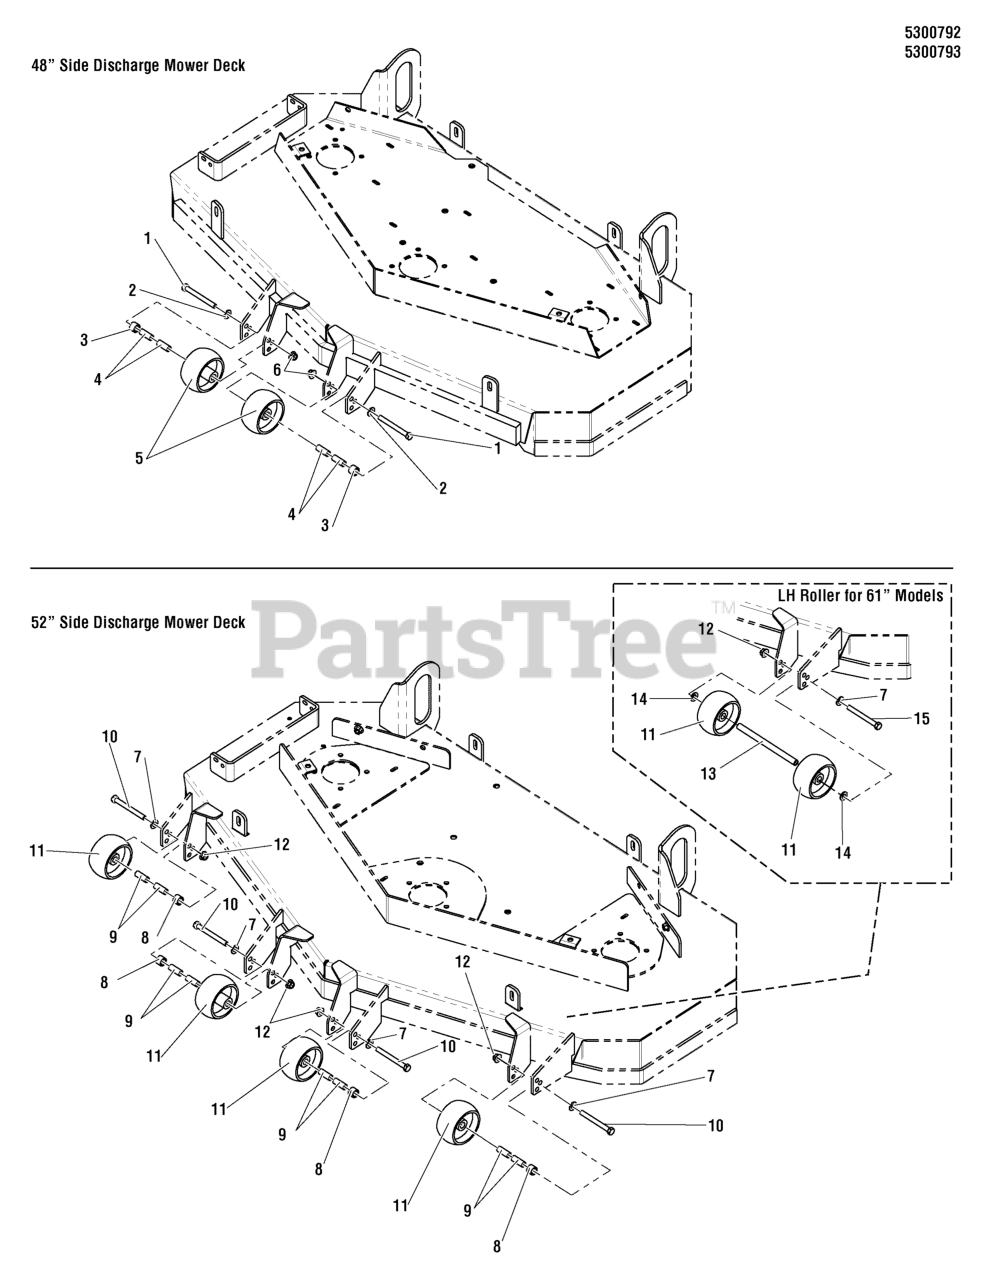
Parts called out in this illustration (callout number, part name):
1	BOLT, 3/8-16 X 3-1/2" GD5 CZ
2	WASHER, 3/8 SAE
3	SPACER, .51 X .75 X .56
4	SPACER, .38 X .50 X 1.25, CZ
5	WHEEL- 2.00 WIDE 3.88 DIA 0.531ID POLY
6	NUT, 3/8-16 HEX NYLOCK FLANGE
7	WASHER, 3/8 SAE
10	BOLT, 3/8-16 X 3-1/2" GD5 CZ
12	NUT, 3/8-16 HEX NYLOCK FLANGE
13	SPACER, .38 X .50 X 5.06
14	WASHER, 1/2 SAE
15	BOLT, 3/8-16 X 6" GD5 CZ
